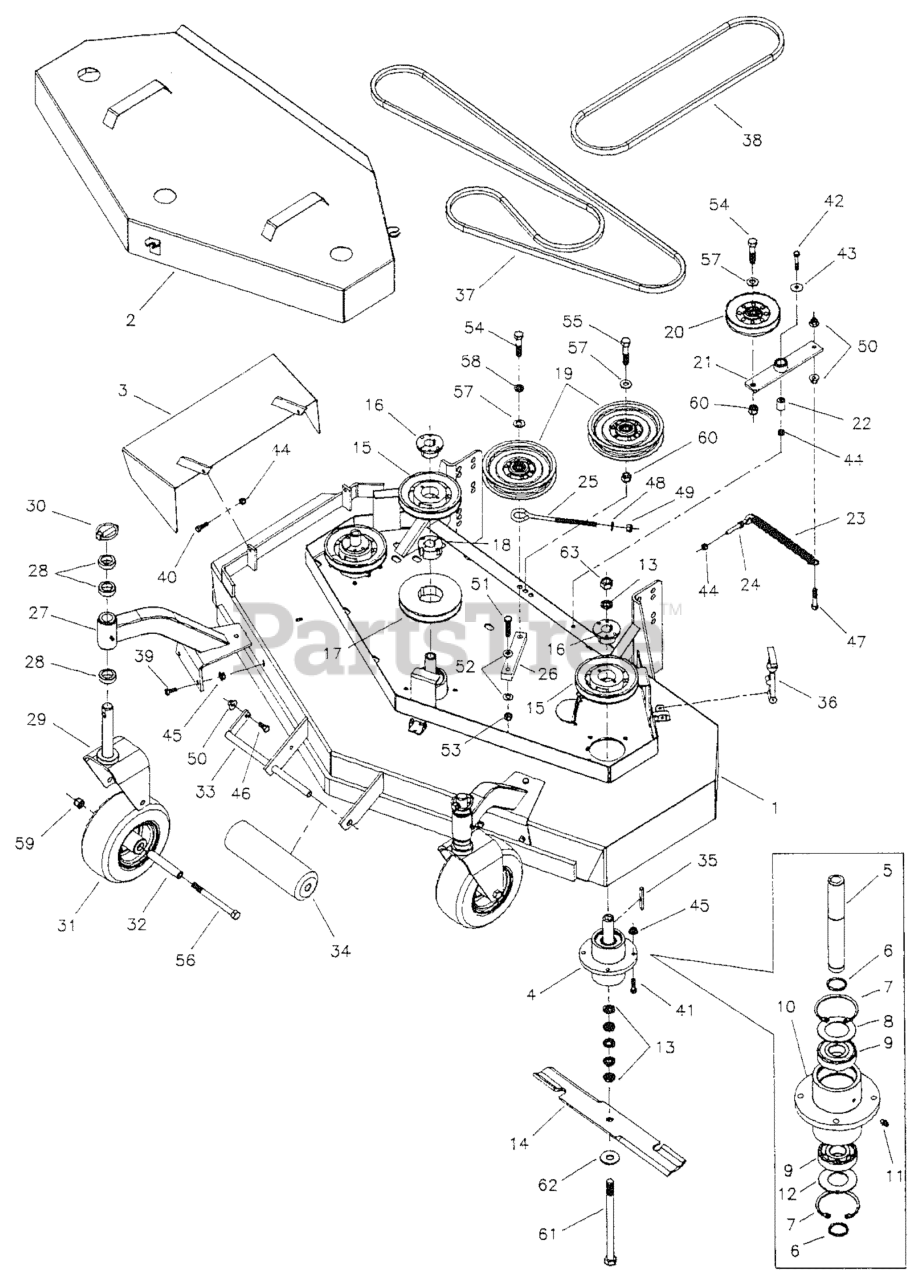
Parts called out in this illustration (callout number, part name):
1	52" Cutter Deck
2	52" Guard
3	CHUTE, DISCHARGE WELDMENT
4	Spindle Assembly
5	Shaft, Spindle
6	Snap Ring, External
7	Snap Ring, Internal
8	Spindle Washer-Top
9	Bearing
10	Housing, Spindle
11	Grease Fitting
12	Spindle Washer-Bottom
13	Spacer, Blade
14	Blade, 18"
15	Pulley, Spindle
16	Bushing, Tapered Hub
17	Pulley, Taper Lock
18	Bushing, Taper Lock
19	Pulley, Backside Idler
20	Pulley, V-Idler
21	Arm, Idler w/ Bushing
21	Bushing, Brass
22	Spacer, Pivot
23	Spring, Extension
24	EYE BOLT,5/16-18 X3.5,2.13THRD,.55EYE,CZ
25	EYE BOLT, 3/8-16 X 8, 3THRD, 1EYE, CZ
26	Arm, Idler
27	Mount, Deck Caster
27	BUSHING, FLANGE
27	Grease Fitting
28	Spacer, Caster
29	Yoke, Caster
30	Pin, Lynch
31	Tire, Caster
32	Axle, Caster Wheel
34	Roller
35	Key, 1/4" Sq. x 2-1/2"
36	Latch, Rubber
37	Belt, Spindle
38	Belt, Deck Drive
39	BOLT, 5/16-18 X 3/4 GD5
40	Bolt, 5/16-18 x I" GD.5
41	Bolt, 5/16-18 x 1-114" GD.5
42	Bolt, 5/16-18 x 1-314" GD.5
43	Washer, 5/16" Fender
44	Nut, 5/16-18 Hex Nylon Lock
45	NUT, 5/16-18 HEX SERRATED FLANGE (LARGE)
46	BOLT, 3/8-16 X 3/4" GD5 CZ
47	BOLT, 3/8-16 X 2, GD5, CZ
48	WASHER, 3/8 SAE
49	NUT, 3/8-16 HEX NYLON LOCK
50	Nut, 3/8-16 Serrated Flange
51	BOLT, 7/16-20 X 1-3/4" GD.5
52	Washer, 7/16" SAE
53	Nut, 7/16-20 Hex Nylon Lock
54	Bolt, 112-20 x 2-114" GD.5
55	BOLT, 1/2-20 X 2-1/4 GD5 CZ
56	Bolt, 1/2-13 x 5-112" GD.5
57	WASHER, 1/2 SAE
58	Washer, 1/2" Lock
59	NUT, 1/2-13 HEX NYLON LOCK
60	NUT, Hex, Nylon Lock, 1/2-20
61	Bolt, 5/8-11 x 9-1/2" GD.5
62	Washer, 5/8" USS
63	Nut, 5/8-11 Hex
